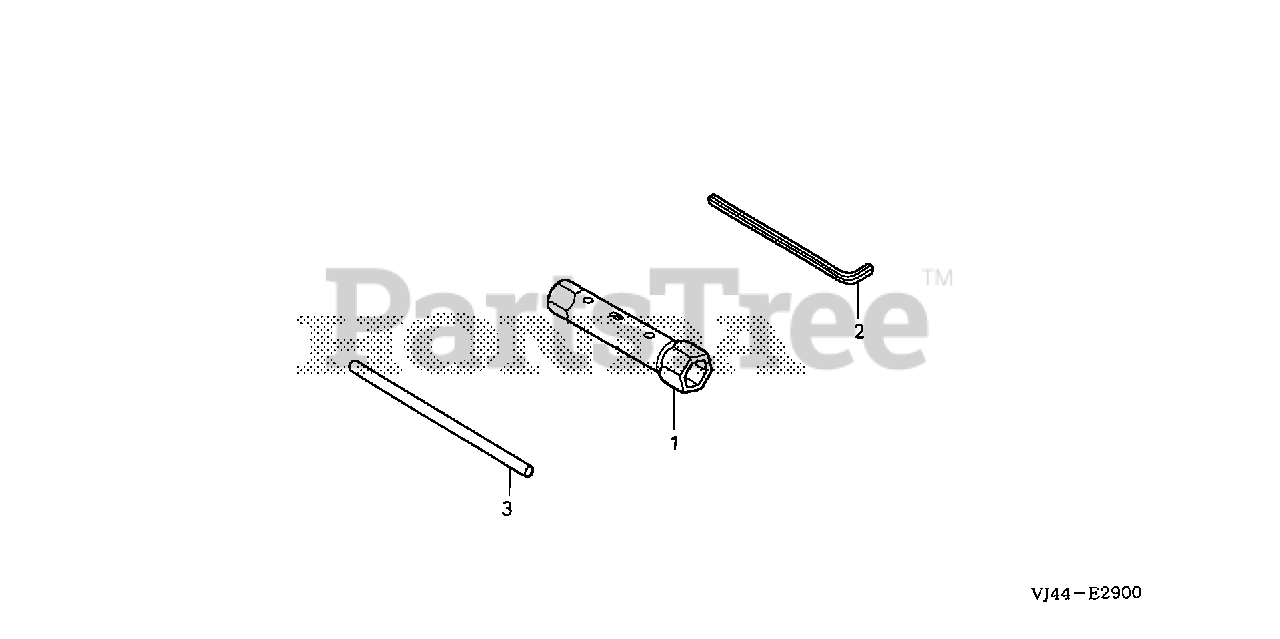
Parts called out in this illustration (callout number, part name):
1	WRENCH, PLUG (16X19)
1	WRENCH, SPARK PLUG
2	WRENCH, HEX. (4MM)
3	BAR A, HANDLE
